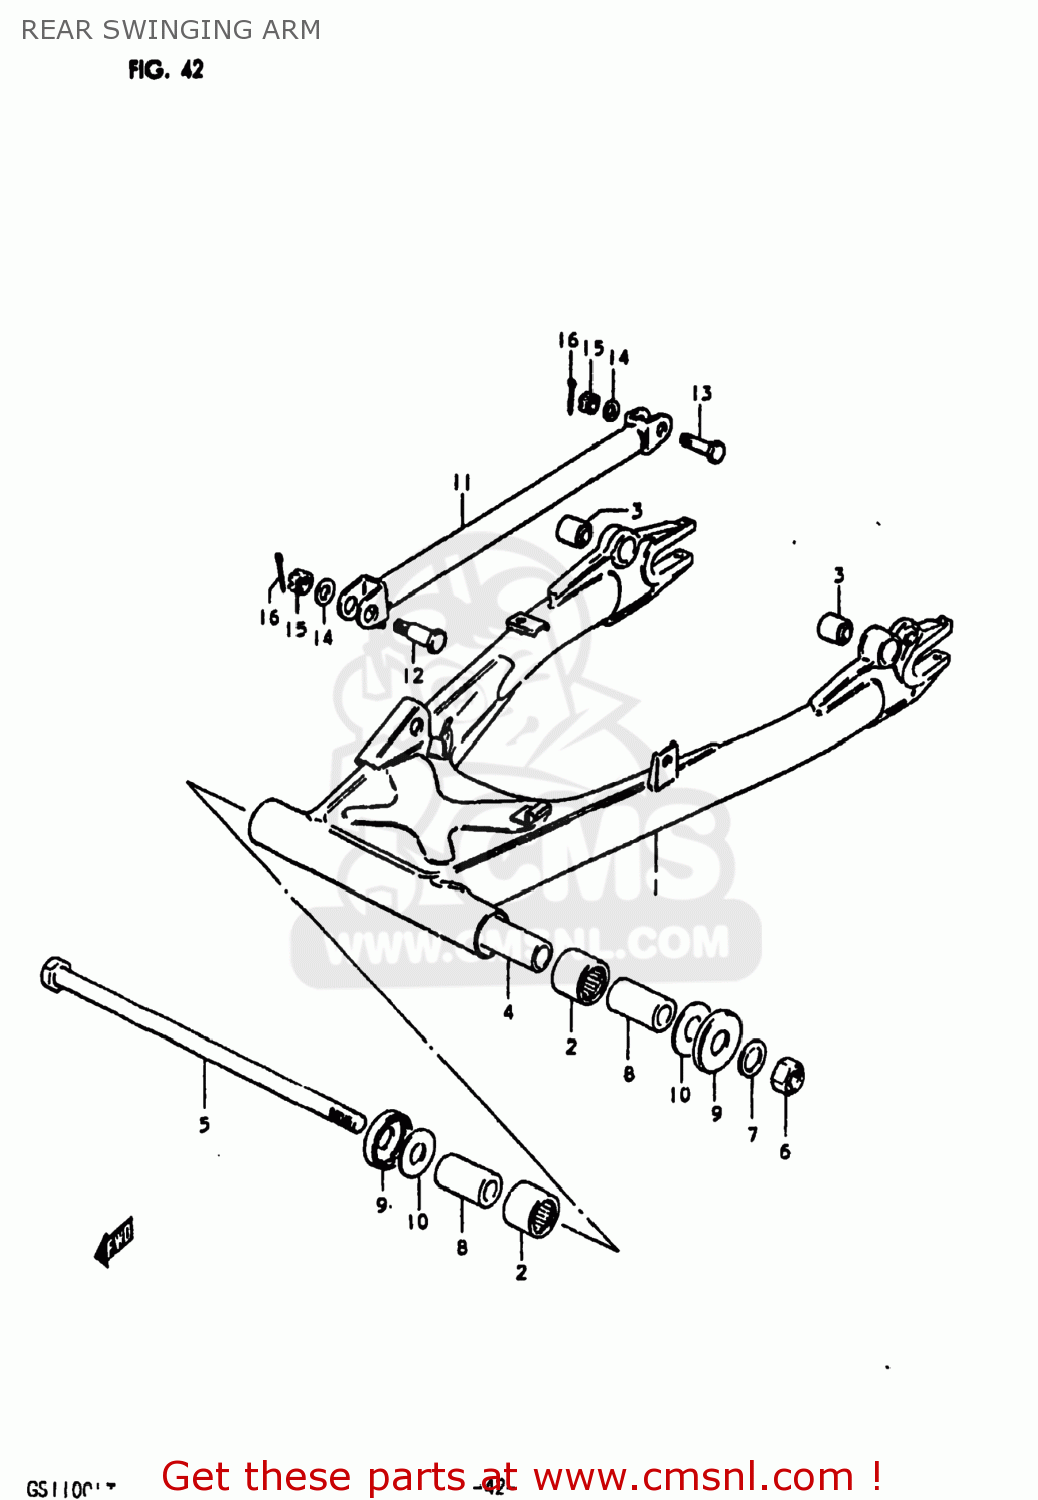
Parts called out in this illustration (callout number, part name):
1	SWING ARM ASSEMBLY,REAR
2	BEARING(25X33X30)
3	BUSH
4	SPACER,RR SWGARM PIVOT CTR
5	SHAFT,REAR SWING ARM
6	NUT 16MM
7	WASHER
8	SPACER,RR SWGARM PIVOT
9	COVER,REAR SWING ARM DUST
10	WASHER
11	LINK,REAR TORQUE
12	BOLT
13	BOLT(10X39)
14	WASHER
15	NUT
16	PIN 20X20
